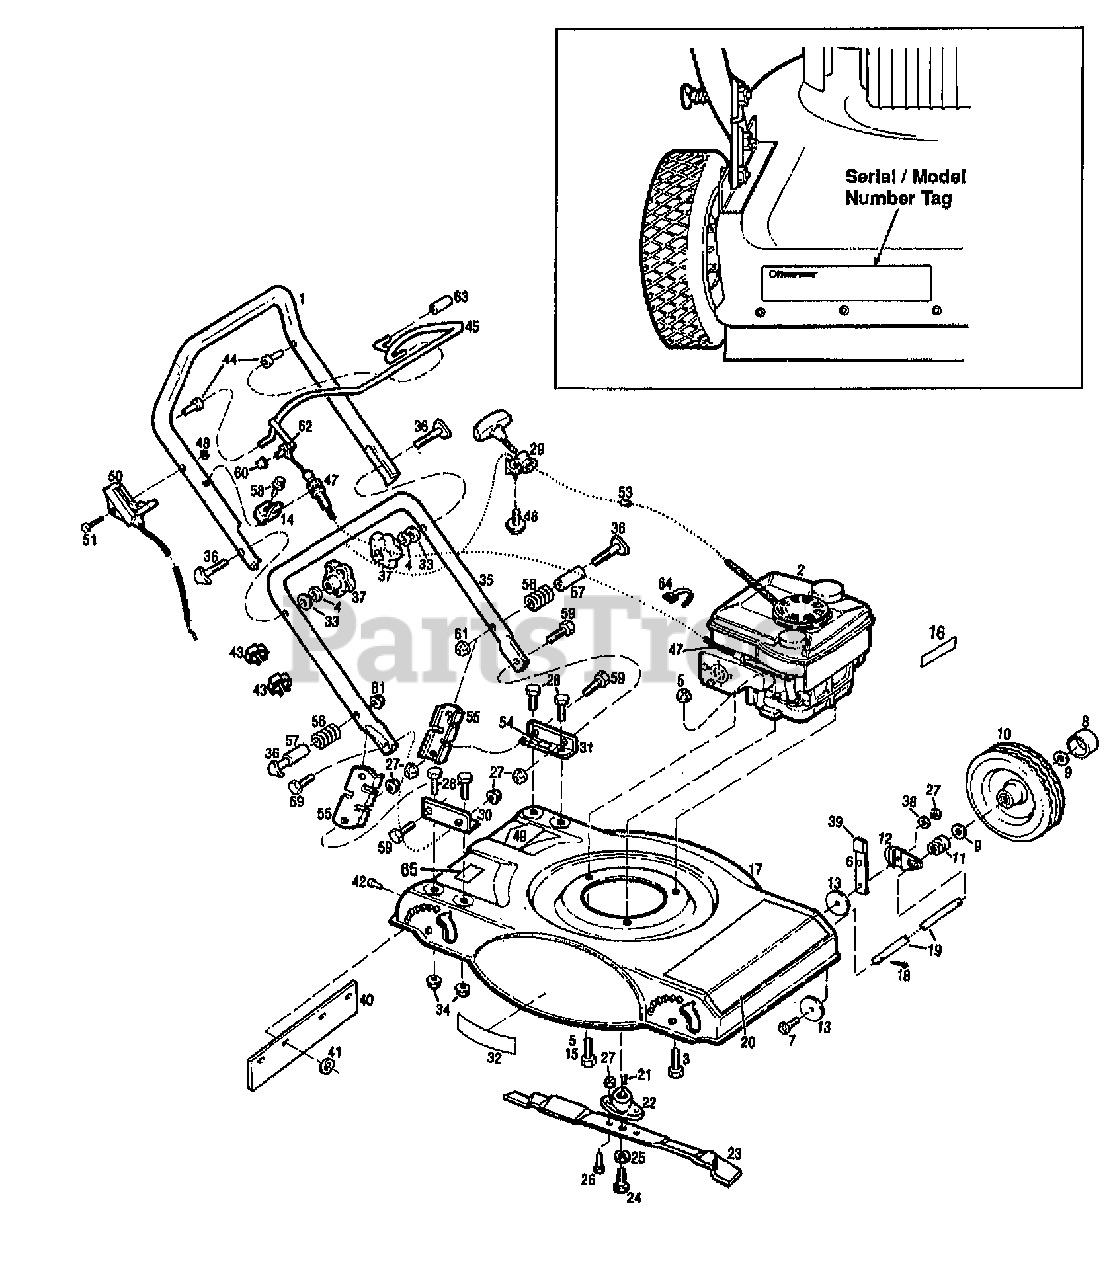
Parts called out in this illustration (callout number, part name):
1	HANDLE-UPPER
2	B & S 3.5 hp #121702-3126
3	SCR-HH 5/16-18X1.5 G5 ZP
4	WASHER-LK .312 ZP
5	NUT-TOP/LK 5/16-18 ZP
6	ASSM-LEVER HEIGHT ADJUST
7	SCR-HFLK 3/8-16X1.00 ZP
8	CAP-HUB
9	WASHER-FLAT .88X.5X.06 ZP
10	ASSM-REAR TIRE & WHEEL
11	BEARING-AXLE
12	ARM-WHEEL MOUNTING
13	WASHER-1.75X.39X.059
14	BRKT-CONTROL CABLE
15	SCR-HH 5/16-18X2.5
16	HEX HD. CAPSCREW 5/16-18 X 2 1/2
17	ASSM-BASE W/DECALS
18	PIN-COTTER .125 X .75 ZP
20	DECAL-LOGO MULCHER 20"
21	KEY-WOODRUFF
22	ASSM-BLADE COUPLING
23	BLADE-CUTTER
24	SCR-SHOULDER
25	WASHER-LK .5
26	SCR-HH 3/8-16X1.0 G5 ZP
27	NUT-LOCK 3/8-16
28	SCR-HFLK 5/16-18X.62 G5ZP
29	GUIDE-ROPE
30	SUPPORT-HANDLE RH
31	SUPPORT-HANDLE LH
32	DECAL-CAUTION
33	WASHER-FLAT 5/16 SAE
34	NUT-HFLK 5/16-18 ZP
35	HANDLE-LOWER
36	SCR-CURVED HD 5/16-18X2.0
38	WASHER-FLAT 3/8 SAE
39	GRIP-VACUCUT
41	WASHER-.88X.2X.059
42	RIVET-POP
43	CLIP-WIRE
44	BEARING-FLANGED
45	CONTROL-ENGINE
46	SCR-HFLK
47	ASSM-CABLE
48	NUT-HT LK 1/4-20
49	DECAL-OPEI CAUTION
50	CONTROL-THROTTLE
51	SCR-HH 1/4-20X1.75 G5 ZP
53	STOP-STARTER ROPE
54	DECAL-HEIGHT ADJUST
55	BRKT-HANDLEBAR
56	SPRING-COMPRESSION
57	SPACER
58	SCR-FLANGE 1/4-20X3/4 GR5
59	SCR-HH 3/8-16X.75 G5 ZP
60	CAP-PUSH ON .312 DIA
61	NUT-HFT/LK
62	RING-GRIP EXT .312 ID
63	GRIP-HANDLE
64	TIE-CABLE NYLON BLACK
65	DECAL-U.S.A.
